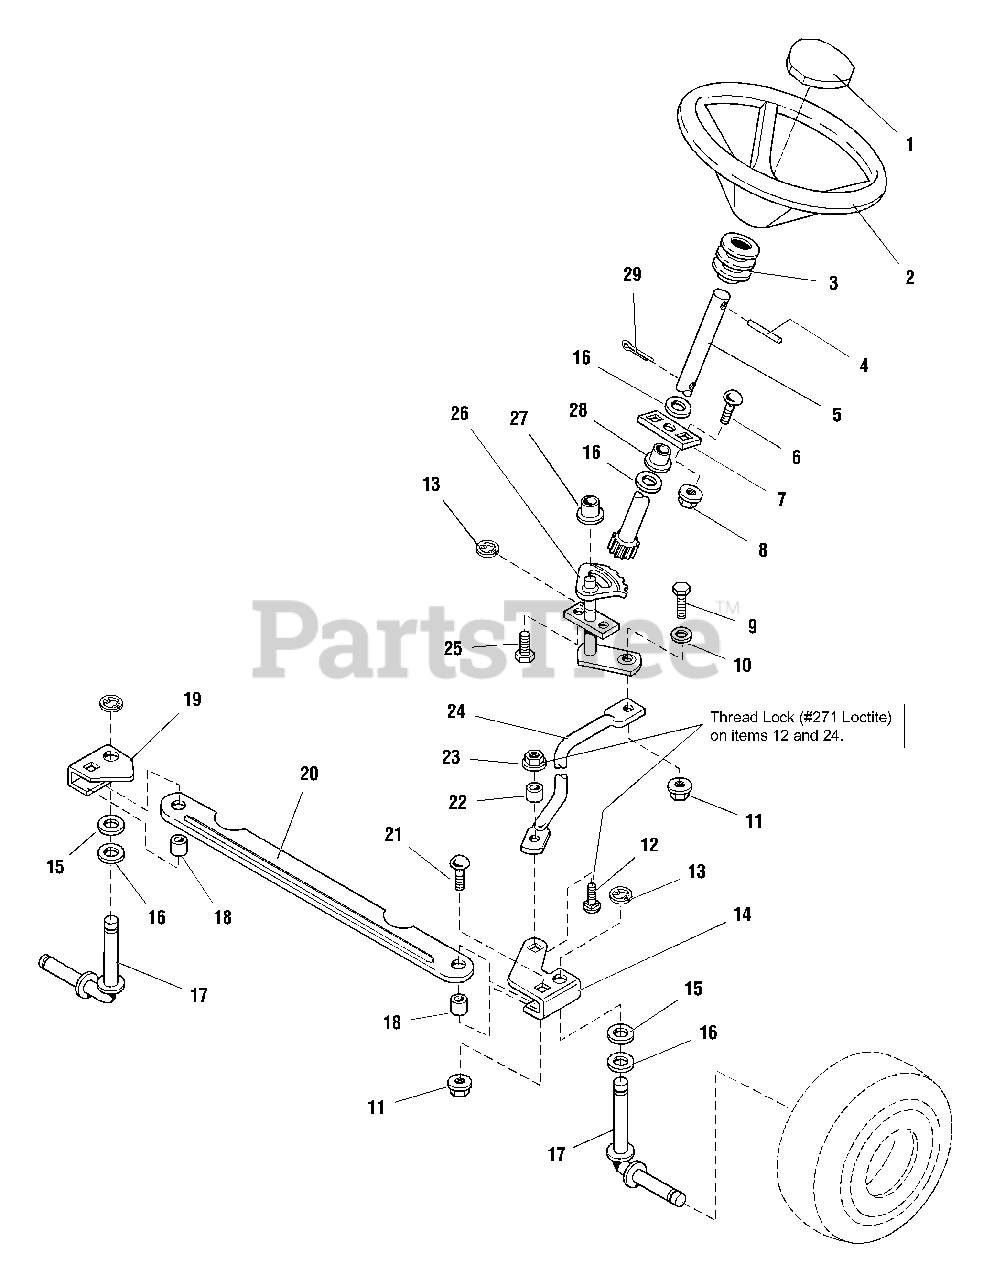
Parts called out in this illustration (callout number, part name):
1	CAP, Steering Wheel
2	STEERING WHEEL
4	PIN, Spring, 5/16 x 2-1/2
5	SHAFT & PINION ASSEMBLY, Steering
6	CARRIAGE BOLT, 3/8-16 x 1
7	PLATE, Steering, Mounting
8	NUT, Hex Flange Whiz Lock, 3/8-16
9	CAPSCREW, Hex Hd, 3/8-16 x 1-1/4
10	WASHER, 3/8
11	NUT, Hex Flange Whiz Lock, 3/8-16
12	CARRIAGE BOLT, 5/16-18 x 1
14	ARM, Steering, L.H.
15	WASHER, 3/4
16	WASHER, 3/4
17	SPINDLE ASSEMBLY
19	ARM, Steering, R.H.
21	CARRIAGE BOLT, 3/8-16 x 1-1/4
23	NUT, Hex Flange Lock, 5/16-18
25	CAPSCREW, Taptite Hex Washer Hd, 5/16-18 x 3/4
26	STEERING GEAR ASSEMBLY
29	PIN, Cotter, 3/16 x 1-1/4
